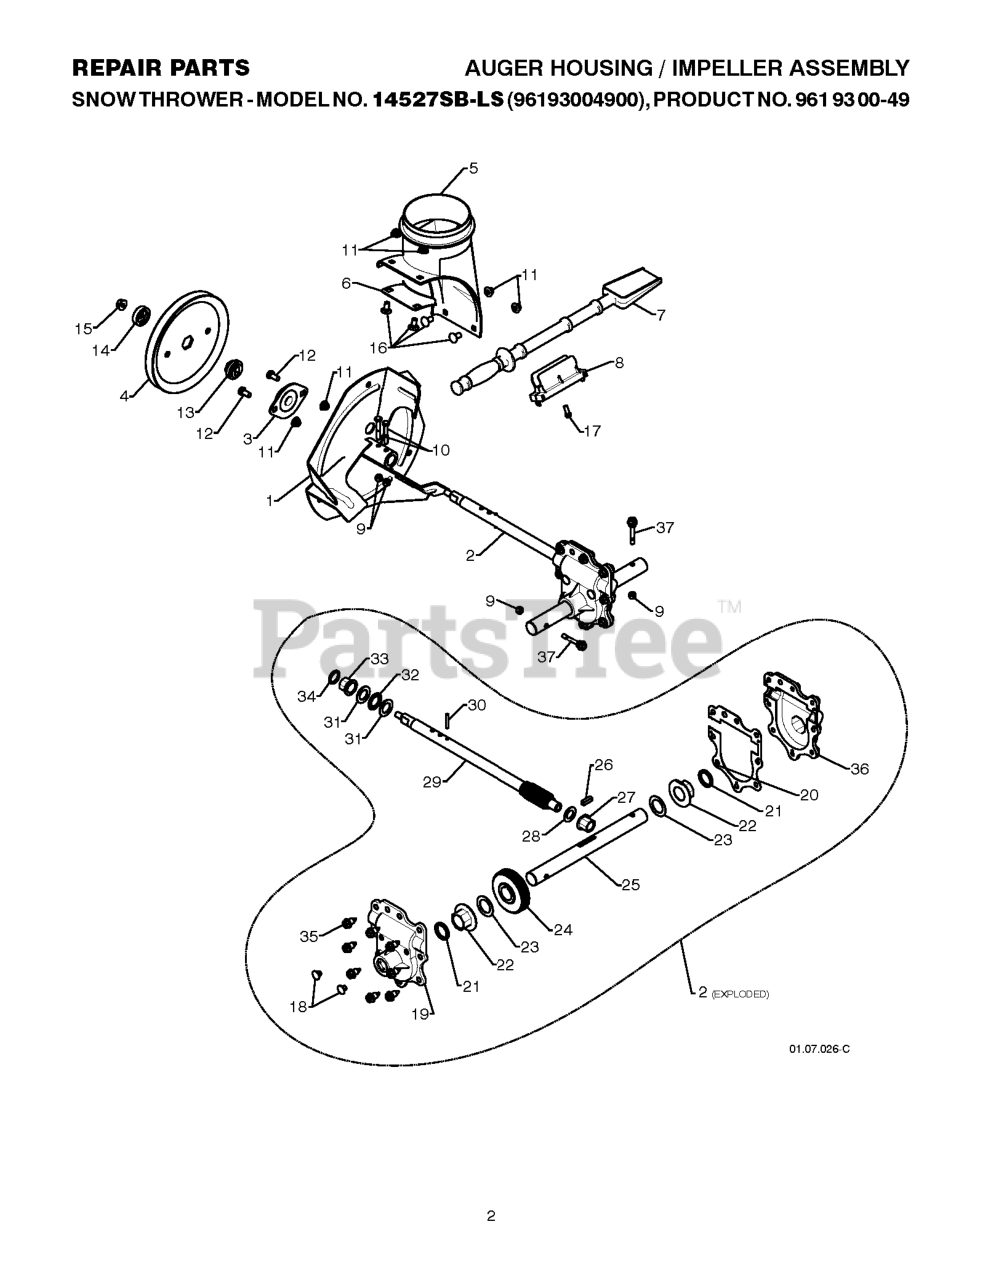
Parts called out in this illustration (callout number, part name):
1	IMPELLER.WELDMENT.BLACK
2	GEARBOX.ASM.AUGER.D-SHAFT
3	BEARING FLANGE
4	PULLEY.FLANGE.IMPELLER
5	BASE DISCHARGE CHUTE
6	BRACKET, CORNER DISCHARGE
7	CLEAN OUT TOOL
8	CLIP.CLEANOUT.TOOL
9	LOCKNUT.NYLOC.1/4-20
10	SCREW.HEX.HD1/4-20X
11	NUTNYLOK.FLRANGE.5/16-18
12	BOLT, HEX HEAD 5/16-18
13	HUB.IMP.PULLEY.D-SHAFT
14	SLEEVE.IMP.PULLEY.D-SHAFT
15	NUT LOCK FLG 3/8-16 UNC
16	BOLT.CARRIAGE.5/16-18X
17	SCREW.HWH.13-16-5.8.BZP
18	CASE PLUG
19	GEAR.BOX.COVER.RIGHT.SIDE
20	GASKET.GEAR.BOX
21	OIL SEAL
22	FLANGE BUSHING-1"
23	WASHER TRUST 1"
24	WORM GEAR
25	AUGER SHAFT
26	KEY, SQUARE 1/4 X .875
27	FLANGE BUSHING-5/8
28	WASHER, THRUST 5/8
29	SHAFT.IMPELLER.D-SHAFT
30	PIN, ROLL 3/16 X 1-1/8
31	WASHER, THRUST 3/4
32	BEARING TRUST 3/4 NTA-1220
33	BUSHING, FLANGE 3/4
35	HEX SCREW-5/16 X 3/4
36	GEAR.BOX.COVER.LEFT.SIDE
37	BOLT.SHOULDER.SHEAR.1/4-20.
